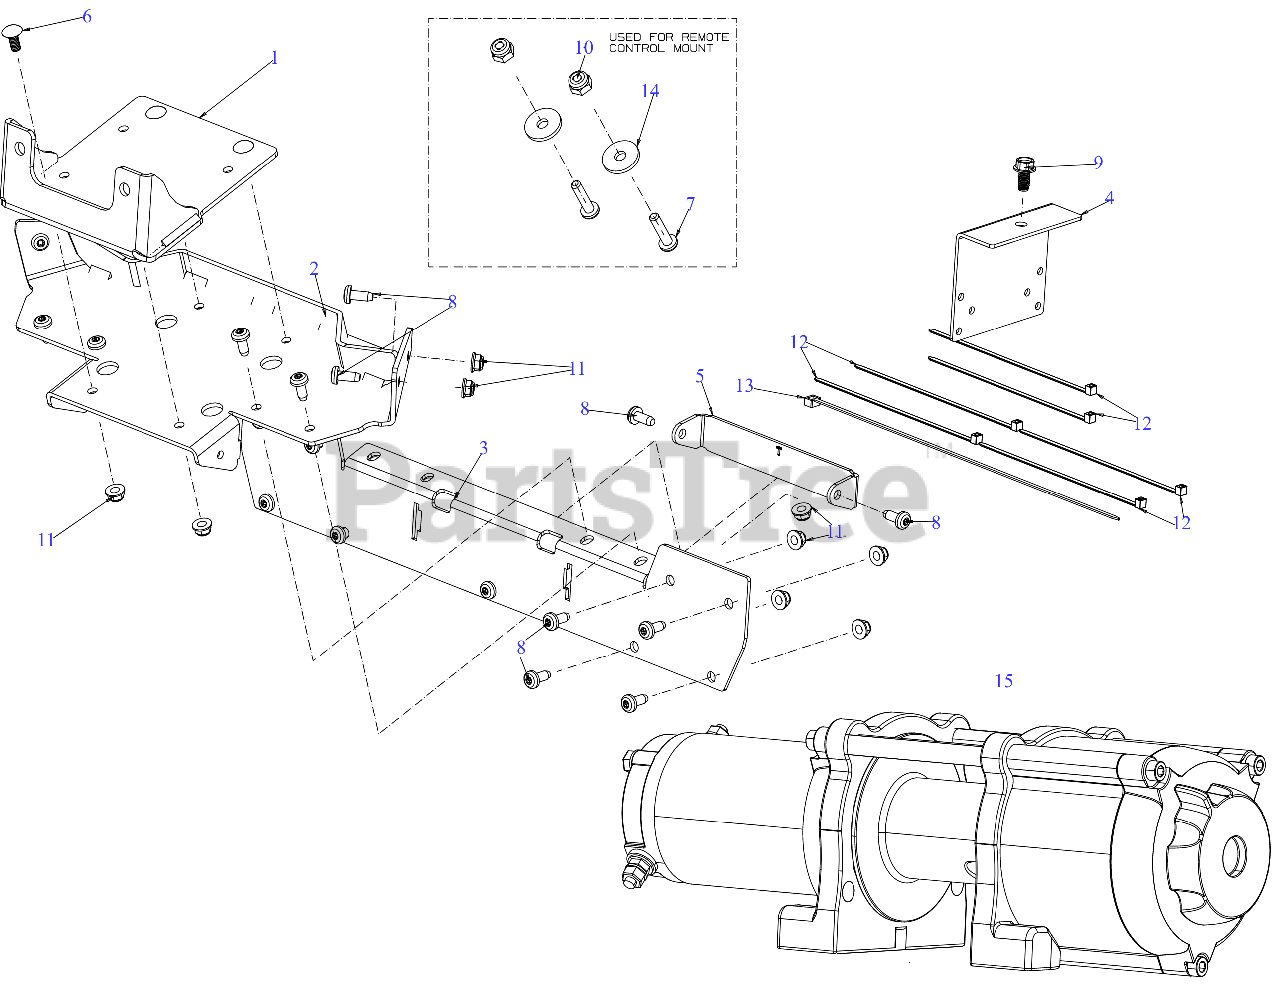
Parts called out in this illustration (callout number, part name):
1	FAIRLEAD MOUNT
2	WINCH MOUNT
3	FRONT MOUNT BRACKET
4	RELAY MOUNT BRACKET
5	SUPPORT BRACKET
6	CARRIAGE BOLT 5/16-18 x .75
7	SCREW #8-32 x .750
8	SCREW 5/16-18 X.75
9	SCREW 3/8-16 x 3/4
11	FLANGE LOCK NUT 5/16-18
12	7" CABLE TIE
13	TIE:CBL:14.5" LONG
14	FLAT WASHER .194x.620x.063
15	WINCH
